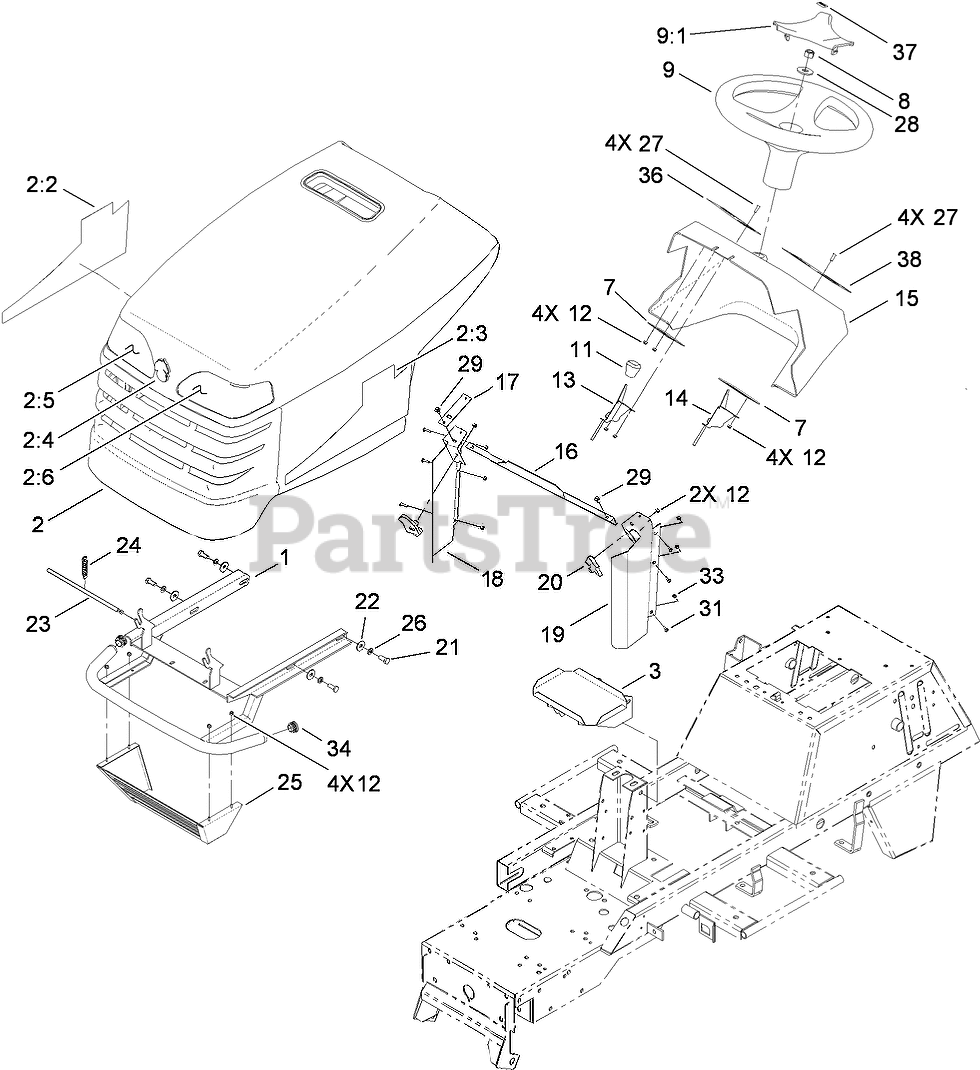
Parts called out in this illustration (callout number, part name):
1	SUPPORT-BUMPER
2	HOOD ASM
2:2	DECAL-HOOD, RH
2:3	DECAL-HOOD, LH
2:4	EMBLEM
2:5	LENS-HEADLAMP, RH
2:6	LENS-HEADLAMP, LH
3	TRAY-BATTERY
8	NUT-LOCK
9	WHEEL-STEERING
9:1	COVER-WHEEL, STEERING
12	NUT-LOCK
13	CONTROL-THROTTLE (TWIN)
14	CONTROL-CHOKE (TWIN)
15	PANEL-DASH
17	BRACKET
18	PANEL-RIGHT
19	PANEL-LEFT
20	LATCH-HOOD
21	SCREW-HH
22	WASHER-PLAIN
23	BAR-SAFETY
24	SPRING-HOOD
25	GUARD-MUFFLER
26	WASHER-LOCK
28	Washer
33	NUT-HEX
34	PLUG-END, TUBE
36	DECAL
37	DECAL
38	DECAL-CHOKE/PTO
